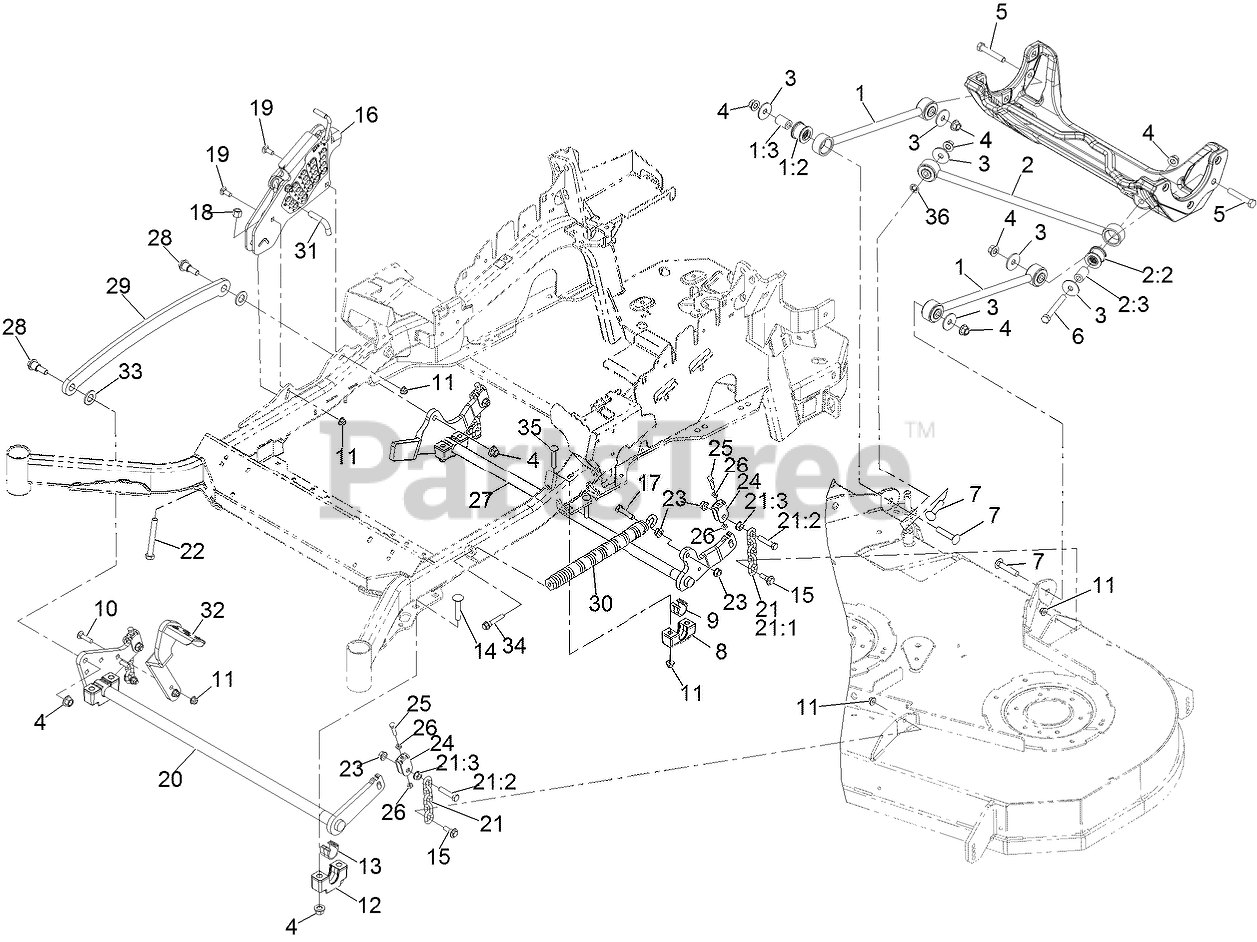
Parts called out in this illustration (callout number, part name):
1	DECK STRUT ASM
1:2	BUSHING-SUSPENSION, RUBBER
2	PANHARD ROD ASM
2:2	BUSHING-SUSPENSION, RUBBER
3	WASHER-THRUST
4	Nut-Lock 1/2-13
5	SCREW-HH
6	SCREW-HH
7	SCREW-CARR
8	SUPPORT-CROSS SHAFT, BEARING REAR
9	BEARING-CROSS SHAFT, REAR
10	SCREW-CARR
11	NUT-HF, NI
12	SUPPORT-CROSS SHAFT, BEARING
13	BEARING-CROSS SHAFT, FRON
14	Bolt-Carriage 1/2-13 X 2 1/2 Spl Neck
15	SCREW-SHOULDER, HHF
16	HOC ASM
17	SCREW-HH
18	NUT-LOCK, NI
19	BOLT-CARR
20	DECKLIFT-FRONT
21	DECK LIFT CHAIN ASM
21:1	CHAIN-LIFT, DECK
21:2	SCREW-HH
22	BOLT-TAP
24	YOKE-ADJUST, DECK
25	SCREW-HH
26	NUT-JAM
27	LIFT-DECK, REAR
28	SCREW-SHOULDER, HHF 1/2-13 X 1.12
29	LINK-LIFT, DECK
30	SPRING-EXTENSION
31	PIN-HOC
32	LEVER-FOOT
33	WASHER-FLAT
34	BOLT-SHOULDER
35	Bolt-Carriage 3/8-16 X 2 1/4
36	NUT-PUSH
